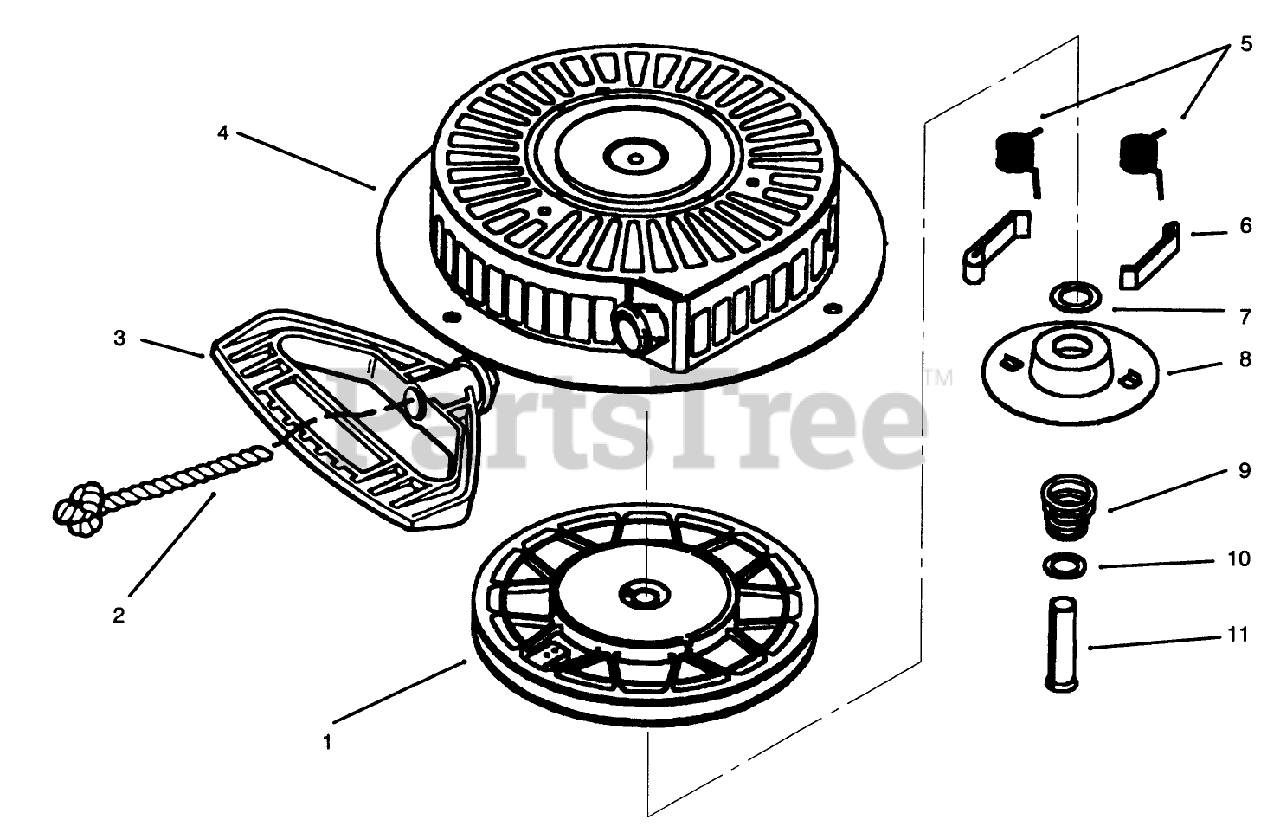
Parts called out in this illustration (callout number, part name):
1	Pulley and Rewind Spring ASM
2	Rope-Starter (98 cut to length)
3	Handle-Starter, Mitten Grip
4	Spring, Pawl
5	Spring-Dog
6	Dog-Starter
7	Washer
8	Retainer
9	Spring-Brake
10	Washer
11	Pin, Spring (Incl. Ref. #7)
